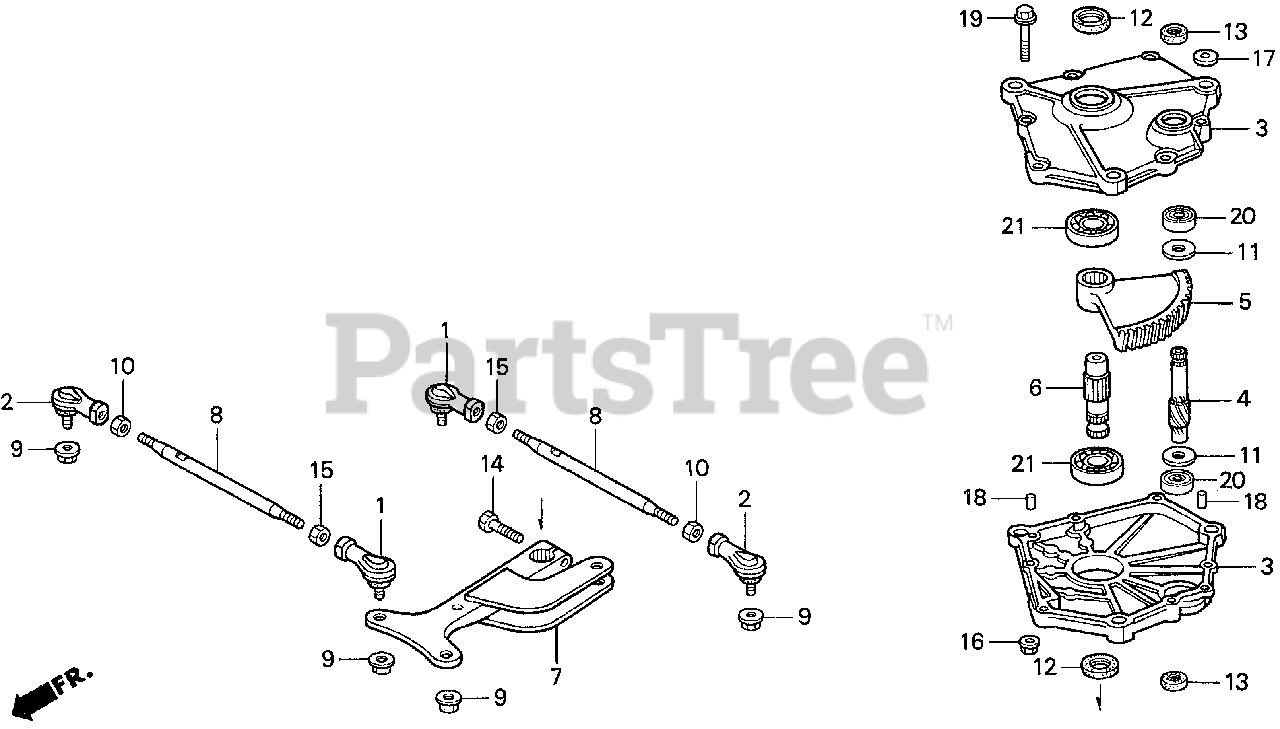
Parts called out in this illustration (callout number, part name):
1	JOINT, R. BALL (ER10)
2	JOINT, L. BALL (ER10)
3	CASE, STEERING GEAR
4	PINION, STEERING
5	GEAR, STEERING
6	SHAFT, STEERING SECTOR
7	ARM, PITMAN
8	TIE ROD, FR.
9	NUT, SELF-LOCK (10MM)
10	NUT, L. HEX. (10MM)
11	WASHER, THRUST (15X1)
12	DUST SEAL (37X25X6)
13	DUST SEAL, CONNECTING ROD PIVOT
14	BOLT, HEX. (10X40)
15	NUT, HEX. (10MM)
16	NUT, FLANGE (6MM)
17	WASHER, PLAIN (10MM)
18	PIN, DOWEL (5X8)
19	BOLT, FLANGE (6X40)
20	BEARING, RADIAL BALL (6202)
21	BEARING, RADIAL BALL (6205)
